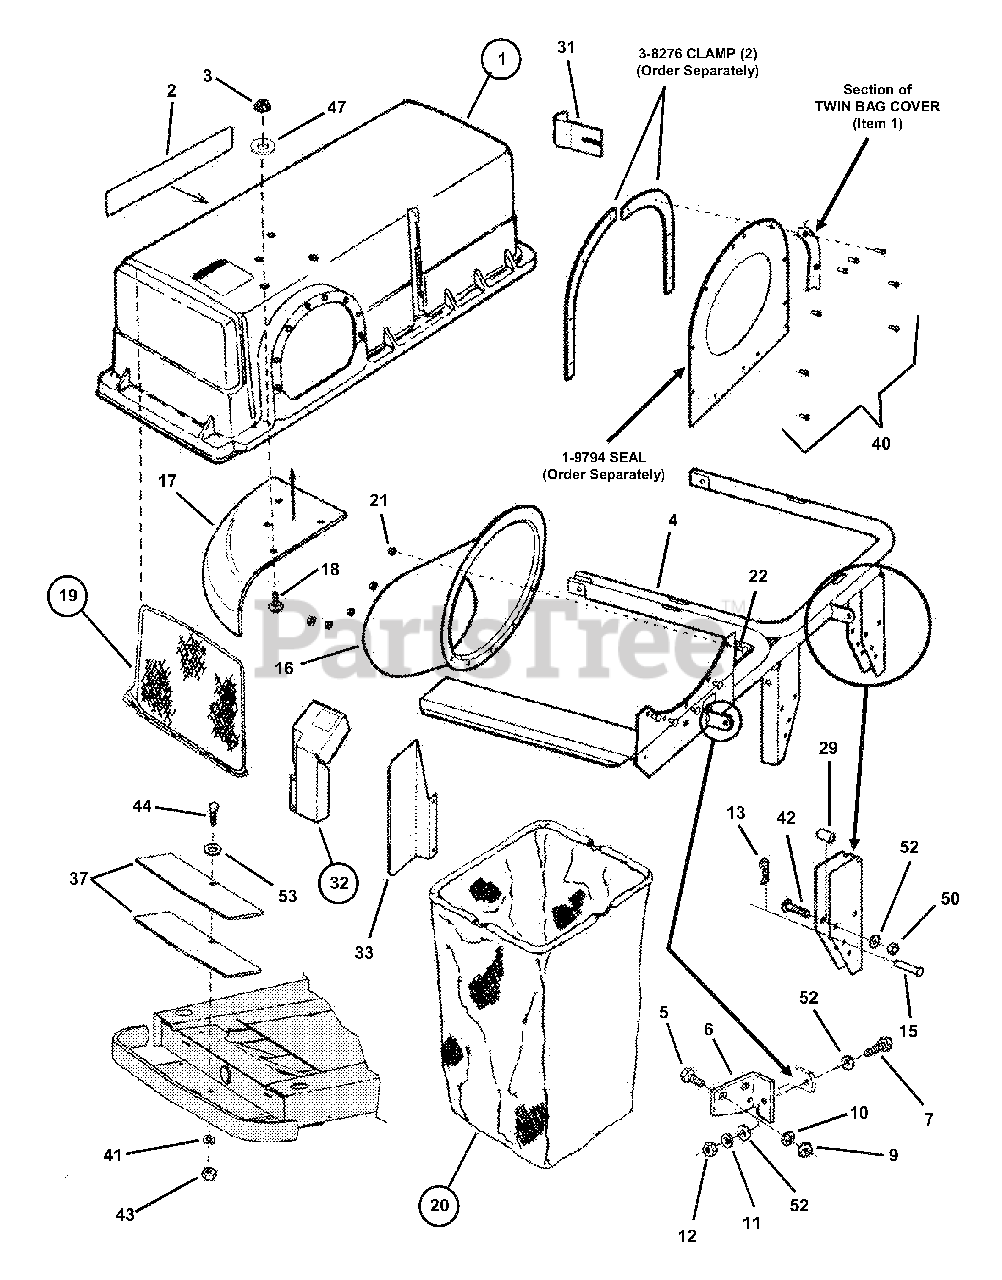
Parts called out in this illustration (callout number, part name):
1	ASS'Y, Cover
2	DECAL, Snapper
3	NUT, 1/4-20 Hex
4	WELDMENT, Frame
5	SCREW, 1/4-28 x 3/4"
6	HINGE, Top
7	SCREW, 5/16-24 x 1"
9	NUT, 1/4-28 Hex
10	WASHER, 1/4" Lock
11	WASHER, 5/16" Split
12	NUT, 5/16-24 Hex Ctr. Lock
13	PIN, 3/32 x 1-1/2" Hair
15	PIN, 5/16 x 1-11/16" Clevis
16	INLET, Twin Bagger
17	SECTOR
18	BOLT, 1/4-20 x 3/4" Carriage
19	ASSEMBLY, Screen (indented items)
20	ASSEMBLY, Bag (indented items)
21	NUT, 1/4-20 Hex Flange
22	BOLT, 1/4-20 x 1/2" Carriage
29	PAD, Bumper Mount
31	SUPPORT, Bumper
32	ASS'Y, Debris Shield
33	GUARD, Muffler
37	WEIGHT, Ballast
40	SCREW, #10-24 x 1/2" Tap
41	WASHER, 1/2" Split Lock
42	BOLT, 5/16-18 x 1-1/2" Carr.
43	NUT, 1/2-13 Hex
44	SCREW, 1/2-13 x 1-1/2" Cap
47	WASHER, 1/4" Flat
50	NUT, 5/16-18 Hex Ctr. Lock
52	WASHER, 5/16" Flat
53	WASHER, 1/2" Flat
